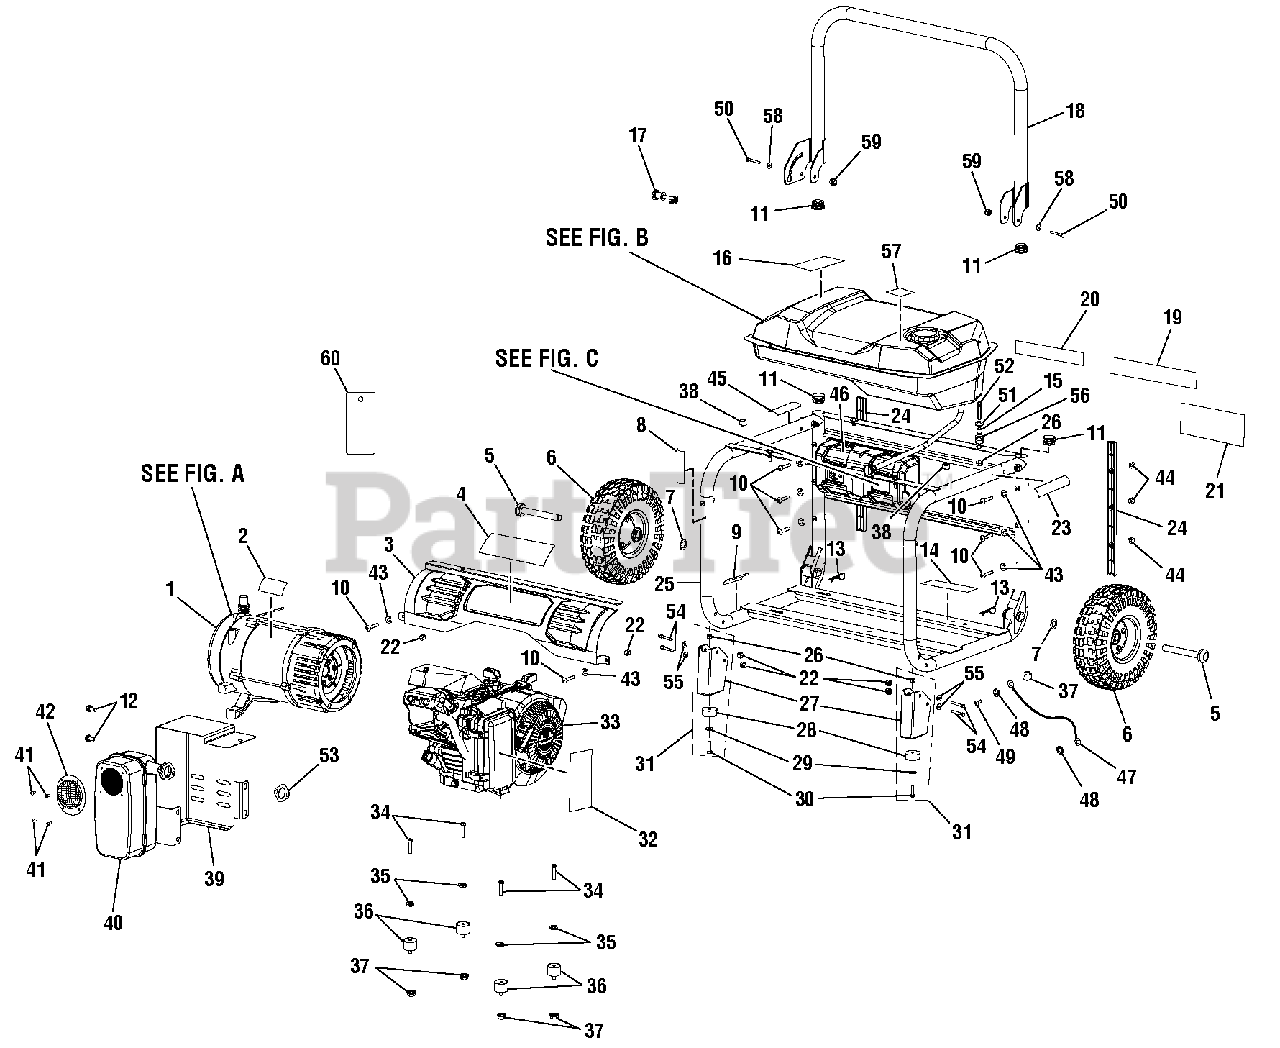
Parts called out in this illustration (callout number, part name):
1	Generator Head Assembly (See Figure A)
2	Data Label
3	Back Panel Assembly
4	Back Panel Logo Label
7	Washer (5/8 in.)
8	Hot Surface Label
9	Label (UL fire warning)
10	Bolt (1/4-20 x 42.5 mm, Torx Hd.)
12	Bolt (5/16-24 x 5/8 in.)
13	Hitch Pin
14	Lubricant Label
15	Spacer (Fuel Tank Isolator)
16	CPSC Label
17	Handle Release Pin Assembly
18	Handle Assembly
19	Danger Label
20	Ground Warning Label
21	Logo Label
22	Lock Nut (1/4-20)
23	Fire Danger Label
24	Frame Slide Rails
25	Frame Assembly
26	Lock Nut (1/4-20)
29	Washer (1/4 in.)
30	Bolt (1/4-20 x 1 in., Hex Hd.)
31	Foot Assembly
32	Starting Instruction Label
34	Bolt (5/16-18 x 1.5 in.)
35	Lock Washer (5/16)
36	Isolator (Generator)
37	Hex Nut (5/16-18, Flange)
38	Rubber Handle Bumper
39	Back Muffler Cover
40	Muffler (Subaru EX30)
41	Screw (8-32 x 3/8 in.)
42	Spark Arrestor
43	Lock Washer (M6)
44	Hex Nut (1/4-20)
45	Pin Release Label
46	Control Panel (See Figure C)
47	Ground Wire Assembly
48	Star Washer (5/16 in.)
49	Bolt (5/16-18 x 3/4 in.)
50	Bolt (M8 x 55 mm, Hex Hd.)
51	Washer (1/4 in.)
52	Bolt (1/4-20 x 1 in.)
53	Muffler Gasket
54	Bolt (1/4-20 x 2 in., T30 Torx Hd.)
55	Washer (1/4 in.)
56	Isolator (Fuel Tank)
57	E85 Label
58	Washer (3/8 in.)
59	Hex Nut (M8)
60	Danger Hang Tag
